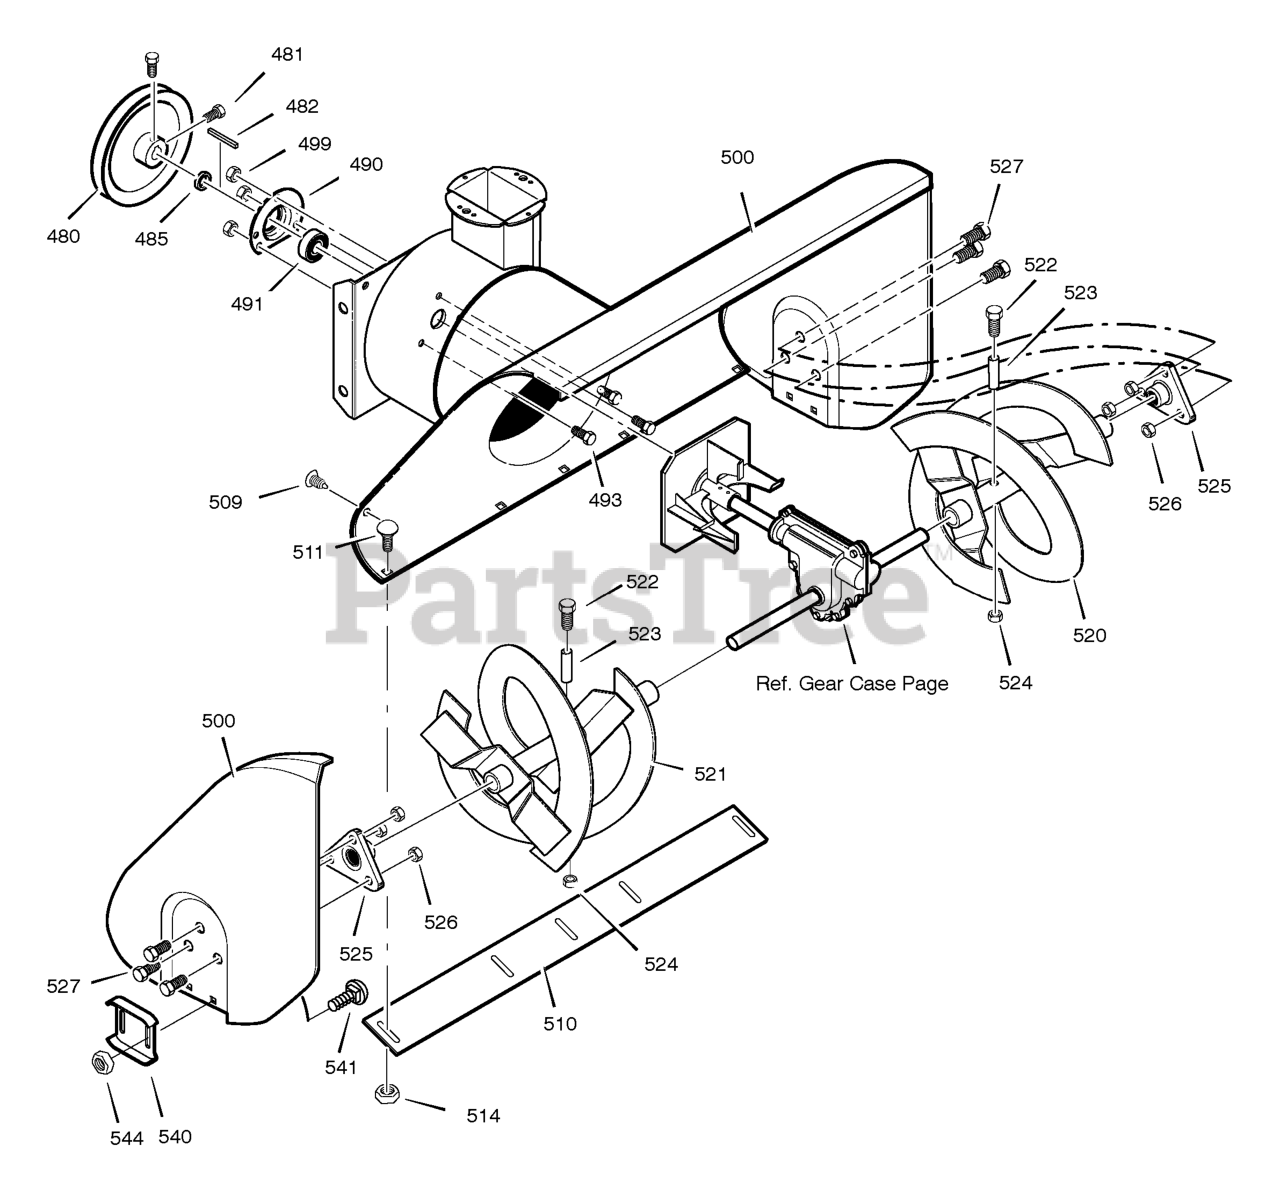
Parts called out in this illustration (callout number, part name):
480	PULLEY, 4L 6.12X .67
481	SCREW, 5/16-18 x 0.63
482	KEY, SQUARE 3/16 X 3/4
485	SPACER, FRICTION PULLEY
490	RETAINER, BALL BRNG
491	BEARING, BALL
493	BOLT, HEX 5/16-18X .50
499	NUT, 5/16-18 HEXWDFLLK
500	HOUSING, ASSY
502	FASTENER, RATCHET
510	BLADE, SCRAPER 24"
511	BOLT, 1/4-20X.75
514	NUT, 1/4-20
520	AUGER, ASSY, LH
521	AUGER, ASSY, RH
522	SCREW, 1/4-20X1.75
523	SPACER, SLEEVE
524	NUT, 1/4-20
525	BEARING,FLANGE
526	NUT, 5/16-18
527	SCREW, 5/16-18 x 0.75
540	SKID, HEIGHT ADJUST
541	BOLT, 5/16-18 X .75
544	NUT, 5/16-18
